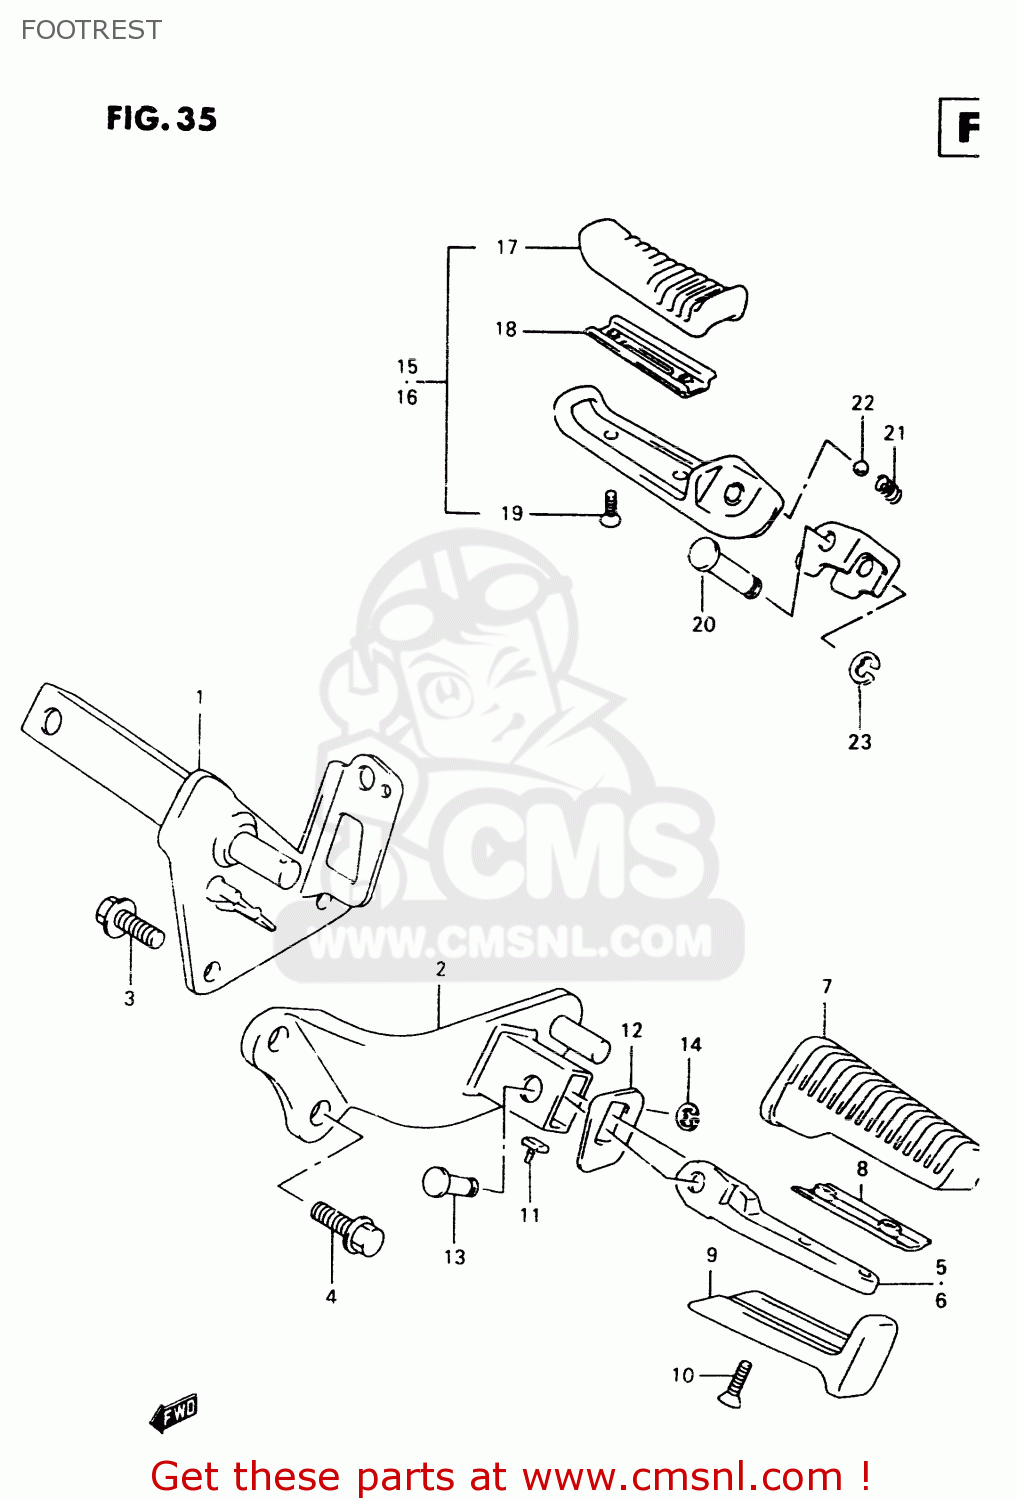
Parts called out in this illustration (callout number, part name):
1	BRACKET,FR FOOTREST,R
2	BRACKET,FR FOOTREST,L
3	BOLT
4	BOLT
5	BAR,FR FOOTREST,R
6	BAR,FR FOOTREST,L
7	RUBBER,FR FOOTREST
8	PLATE,RUBBER STOPPER
9	COVER,FR FOOTREST
10	SCREW(5X20)
11	CUSHION,FR FOOTREST BAR
12	WASHER,FR FOOTREST
13	PIN
14	E.RING
15	FOOTREST ASSY,PILLION,R
16	FOOTREST ASSY,PILLION,L
17	RUBBER,PILLION FOOTREST
18	PLATE,RUBBER STOPPER
19	SCREW(5X16)
20	PIN
21	SPRING
22	BALL
23	E.RING
